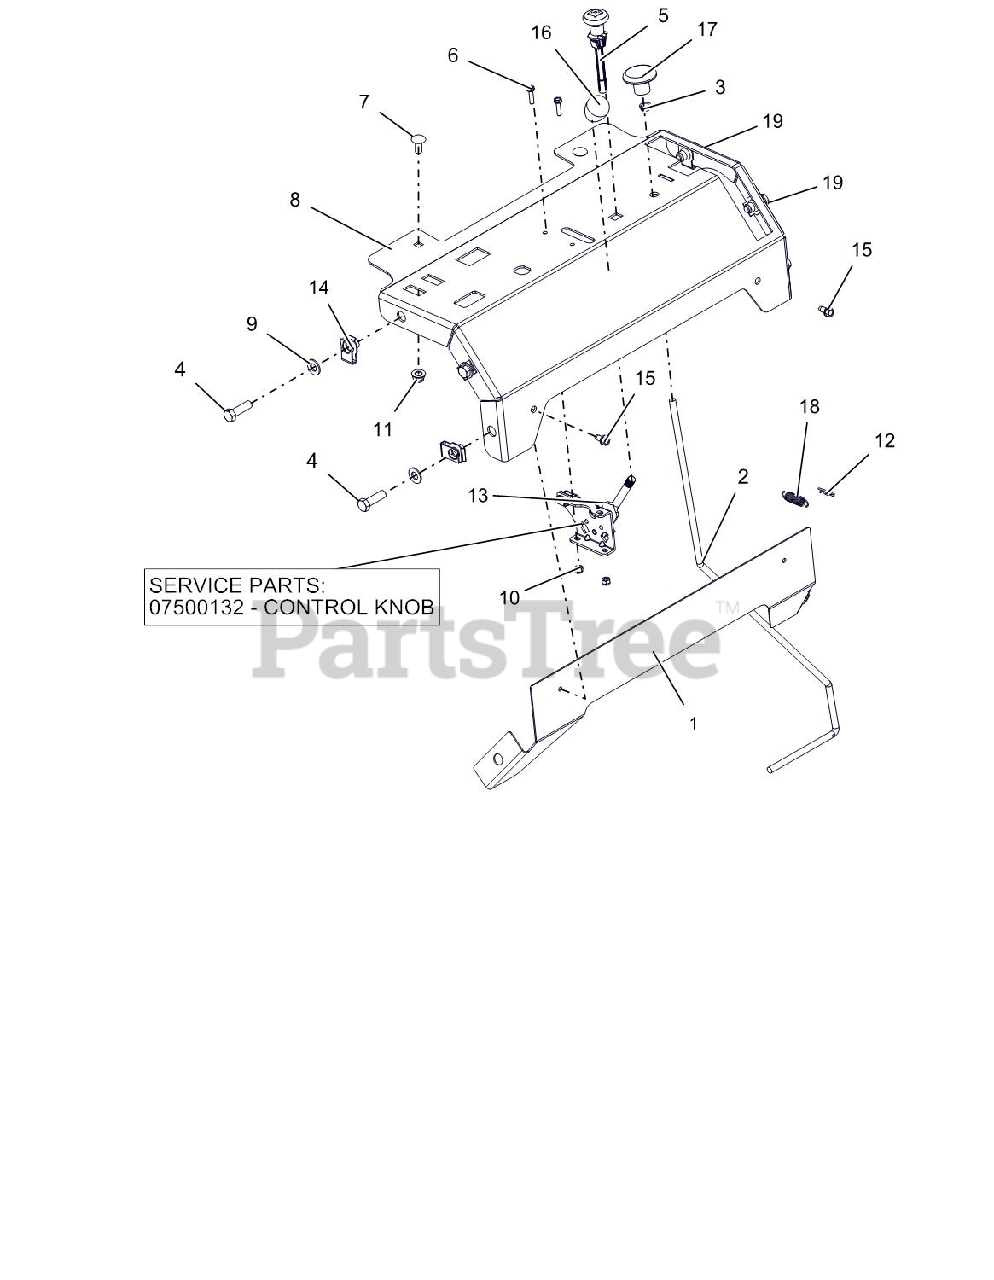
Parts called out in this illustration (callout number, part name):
1	PLATE, FRONT BACKER
2	WIREFORM, TRAILER LOCK
3	BUSHING, POLYLINER-.38 SNAPIN
4	@BLT-HEX .38-16X1.25 GR5 YWZC
5	CABLE, CHOKE (SNAP IN)
6	@SCR-MCH 10-24X.75 HWH YWZC
7	@BLT-RHDSSQNK .31-18X.75 G5YZ
8	KIT, SERVICE COMP. STANCE DASH
9	@WSHR-FL-STL.406X.812X.065 YWZ
10	@NUT-LK-NYL 10-24 W/INSRT YWZC
11	@NUT-LK-NYL-FLG .31-18 YWZC
12	PIN-HAIR, ENDRIES #25 YWZC
13	CABLE, PRO-CONTROL
14	NUT-RTNR .375-16X.37
15	SCR-TAP .25-20X.50 HWH TR YWZ
16	KNOB-CONTROL-BLACK .38-16X.50
17	KNOB, PUSH-PULL .312-18
18	SG-TENS .048X.44X1.75 WLD 9
19	@BLT-HEX .38-16X1.00 GR5 YWZC
20	KNOB-CONTROL-BLACK .38-16X.50
